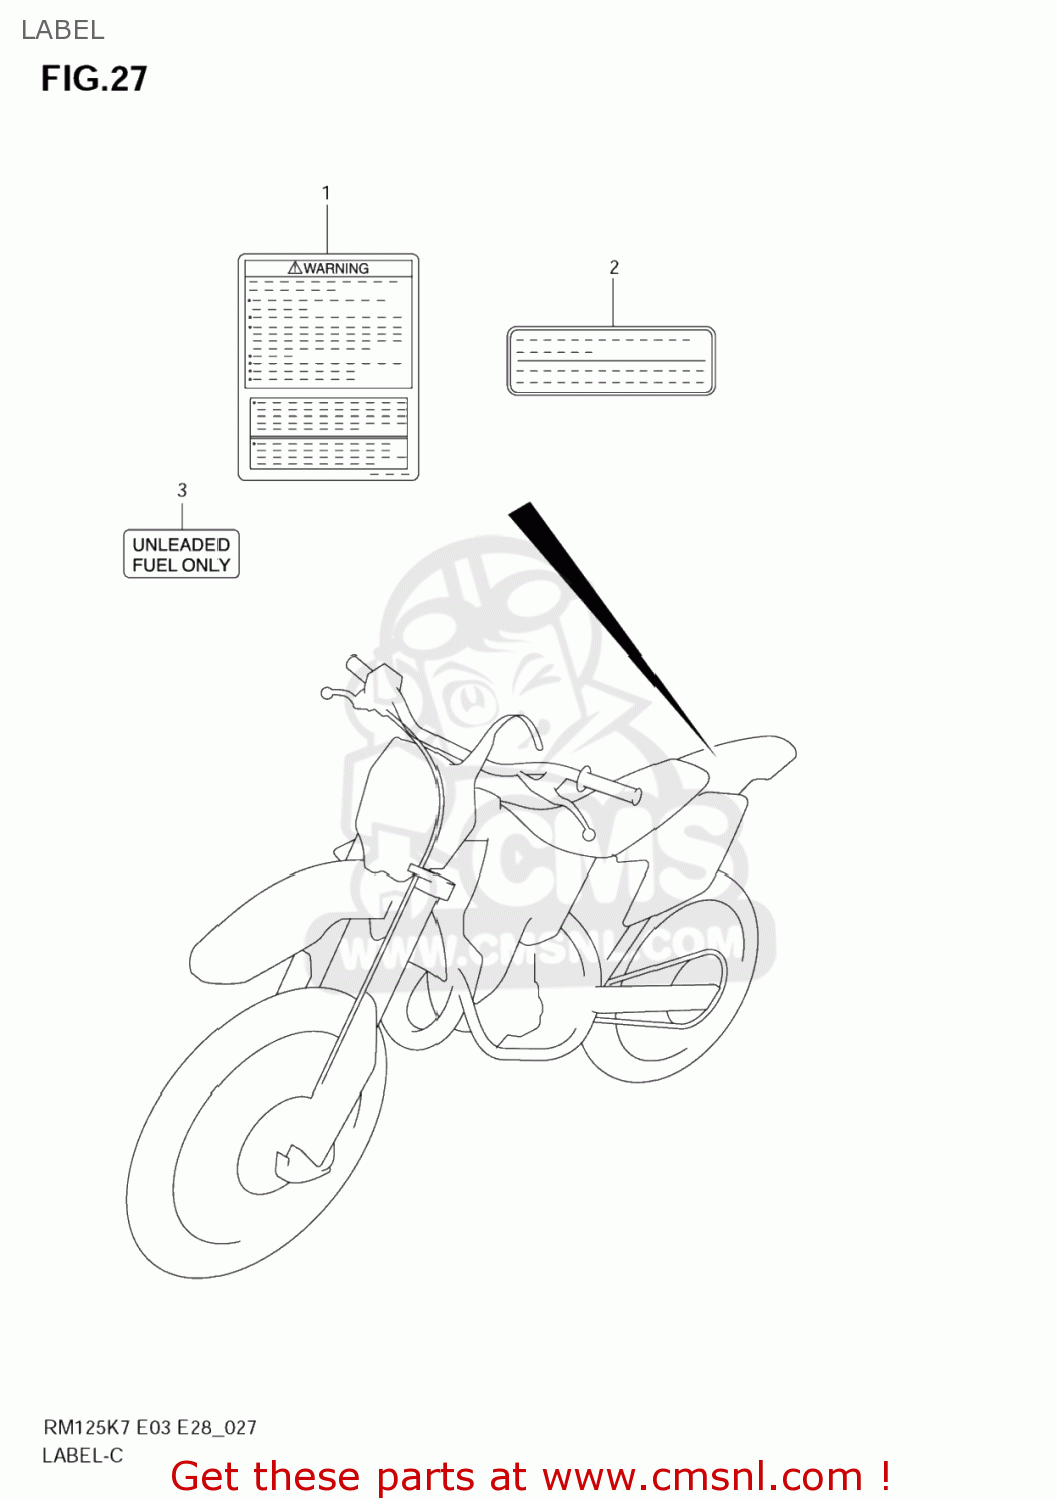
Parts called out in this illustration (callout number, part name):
1	LABEL,WARNING
2	LABEL,WARNING NO.2
3	LABEL,UNLEADED FUEL
4	MANUAL,OWNER'S
